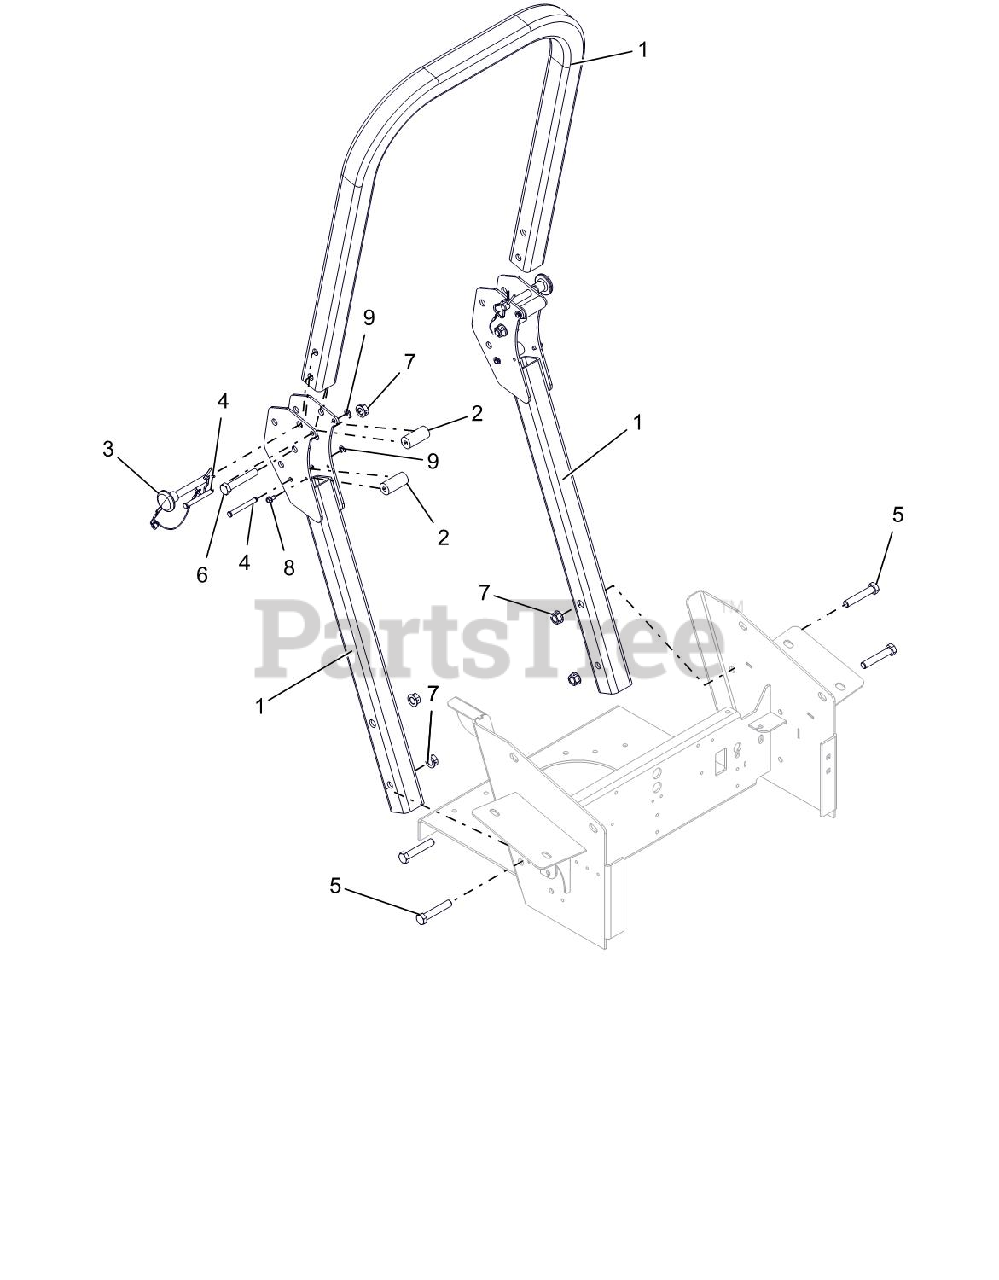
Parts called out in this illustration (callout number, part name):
1	ROPS, PT/PT100 REPLACEMENT
2	BUMPER, ROPS ANTI-VIBRATION
3	PIN, ROPS W/LANYARD
4	PIN, 5/16 X 2-9/16 WITH GROOVE
5	BOLT, HEX 0.5-13X2.75 GR5
6	BOLT, HEX 0.5-13X3 GR5
7	NUT-LK-CTR-FLG .50-13 YWZC
8	SCR-TAP .25-20X.50 HWH TR YWZ
9	RING, RETAINING-E .31X.025 - BRIGHT ZINC
